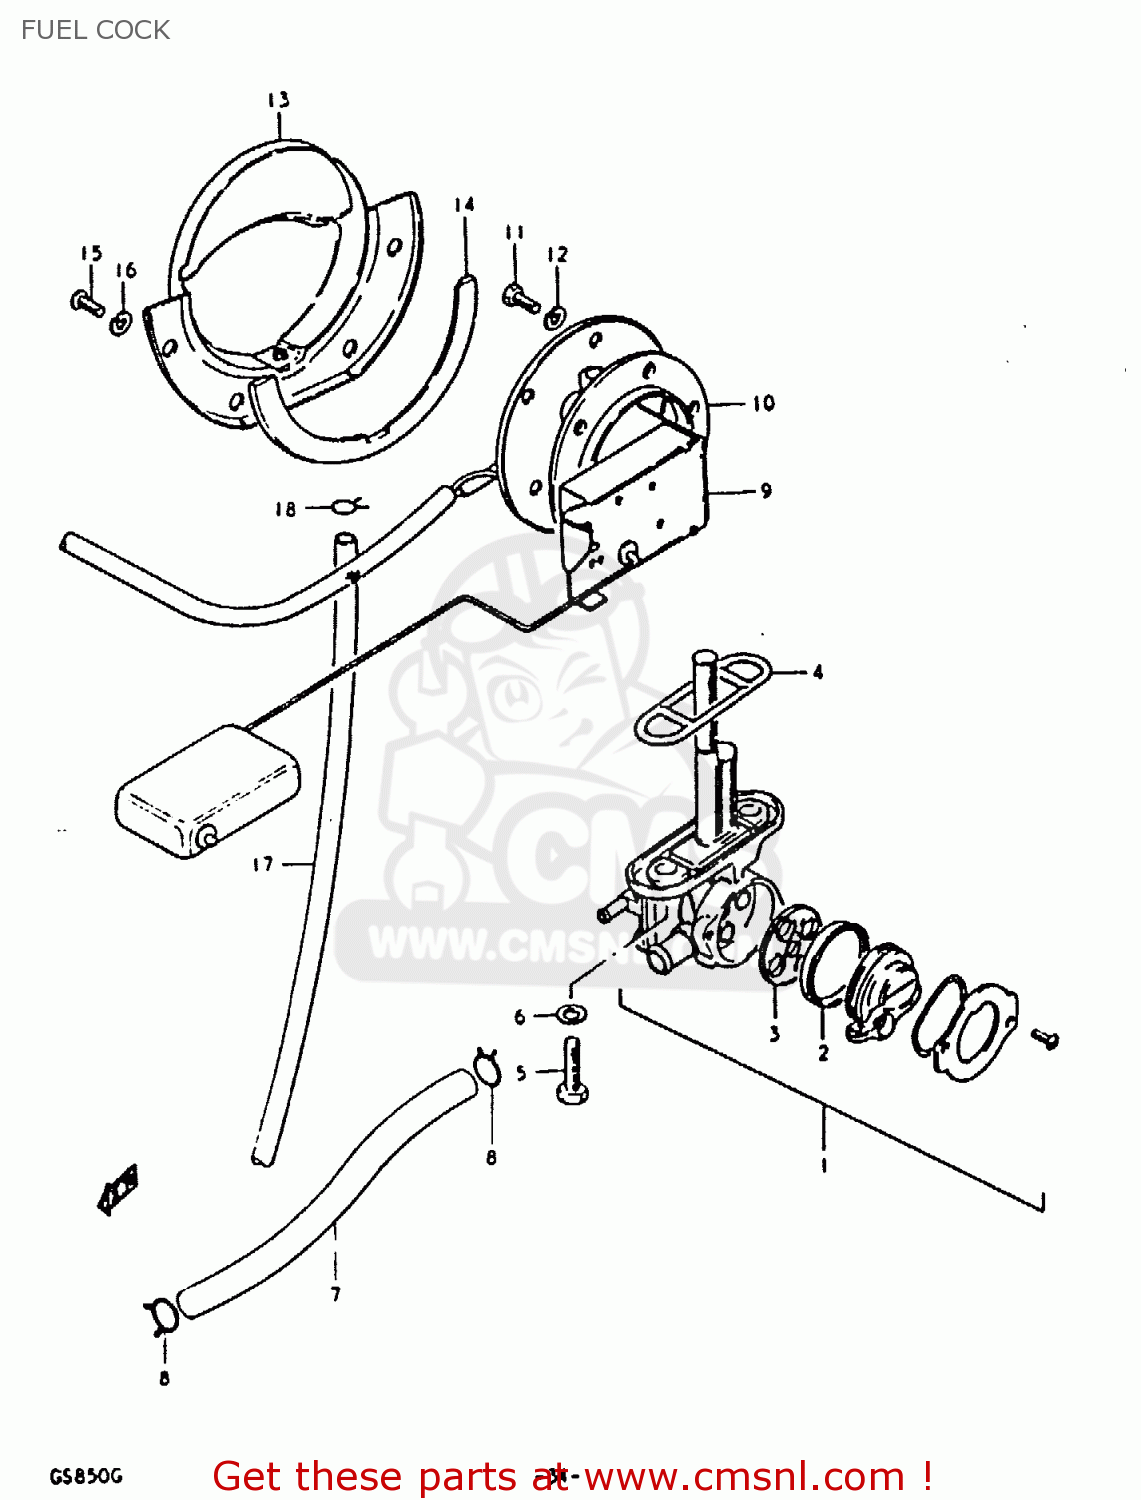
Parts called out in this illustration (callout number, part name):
1	COCK ASSY,FUEL
2	V SEAL,FUEL COCK
3	GASKET (NAS)
4	GASKET, FUEL COCK (NAS)
5	BOLT(6X20)
6	GASKET
7	HOSE
8	CLIP
9	GAUGE ASSEMBLY,FUEL LEVEL
10	GASKET,FUEL LEVEL GAUGE (NAS)
11	BOLT 5X16
12	LOCK WASHER
13	PLATE,FUEL DRAIN
14	GASKET,FUEL DRAIN PLATE (NAS)
15	SCREW
16	LOCK WASHER
17	HOSE
18	CLIP
